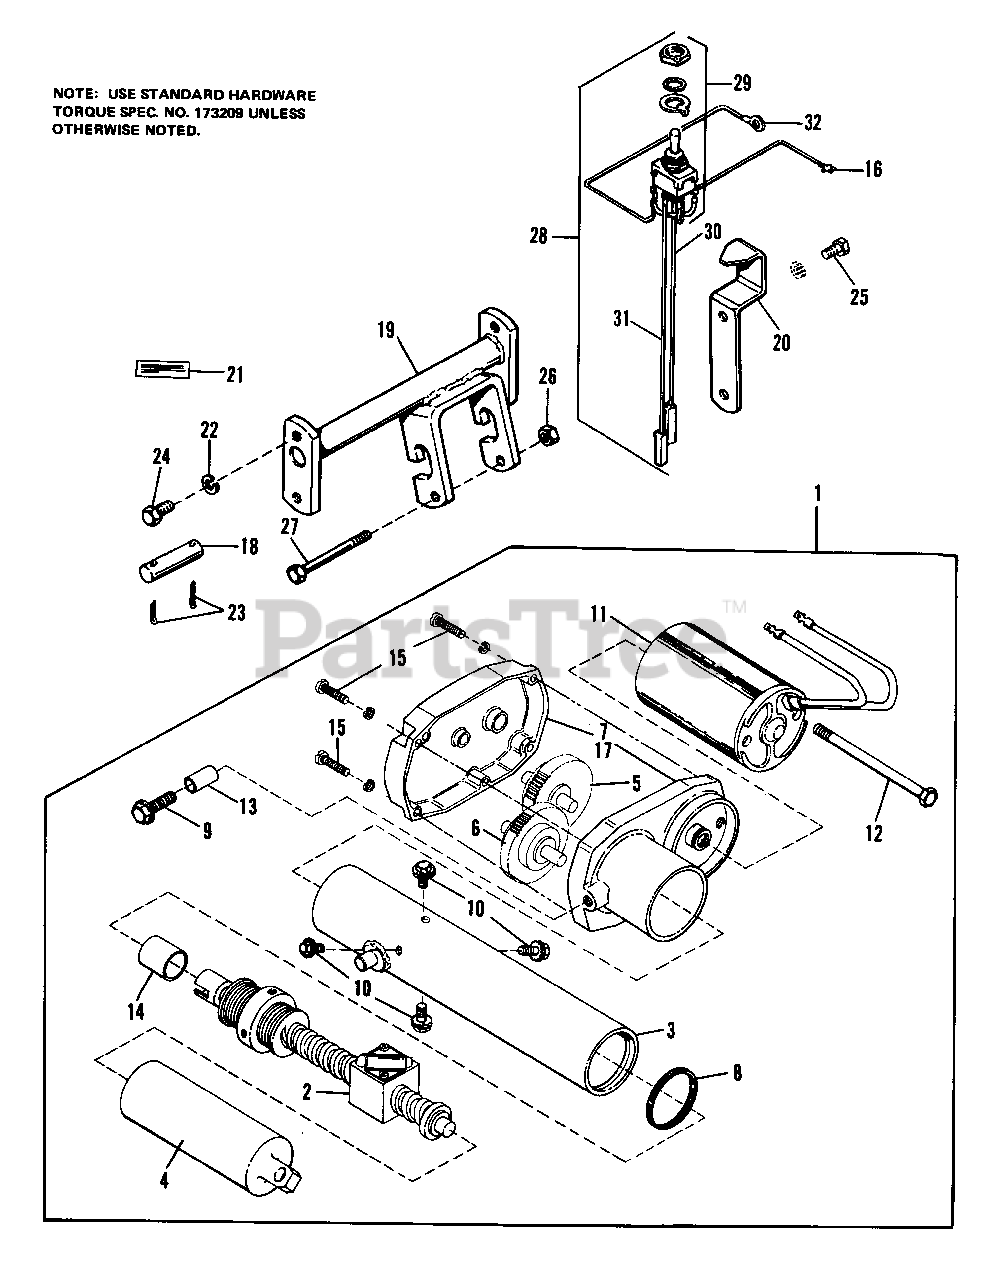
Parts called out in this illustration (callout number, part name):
1	LIFT ASSY, Power
2	BEARING ASSY, Ball, Screw & Brk.
3	TUBE ASSY, Outer
4	TUBE ASSY, Inner
5	GEAR ASSY
6	GEAR ASSY
9	SCREW, Thd. Forming
10	SCREW, Thd. Cutting
14	SLEEVE, Coupling
15	SCREW, Filister Hd.
16	WIRE, Sw. to Ignition
19	SUPPORT ASSY, Pump
20	STOP, Pointer
21	DECAL, Lift Control
22	LOCKWASHER, Spring, 3/8
23	PIN, Cotter, 3/32 x 3/4
24	CAPSCREW, Hex Hd., 3/8-16 x 5/8
25	CAPSCREW, Hex Hd., 3/8-16 x 1/2
26	NUT, Hex Lock, 5/16-18
27	CAPSCREW, Hex Hd., 5/16-18 x 3-1/4
28	SWITCH & HARNESS
29	SWITCH, Elec.
30	WIRE, Sw. to Lift
31	WIRE, Sw. to Lift
32	WIRE, Sw. to Ground
